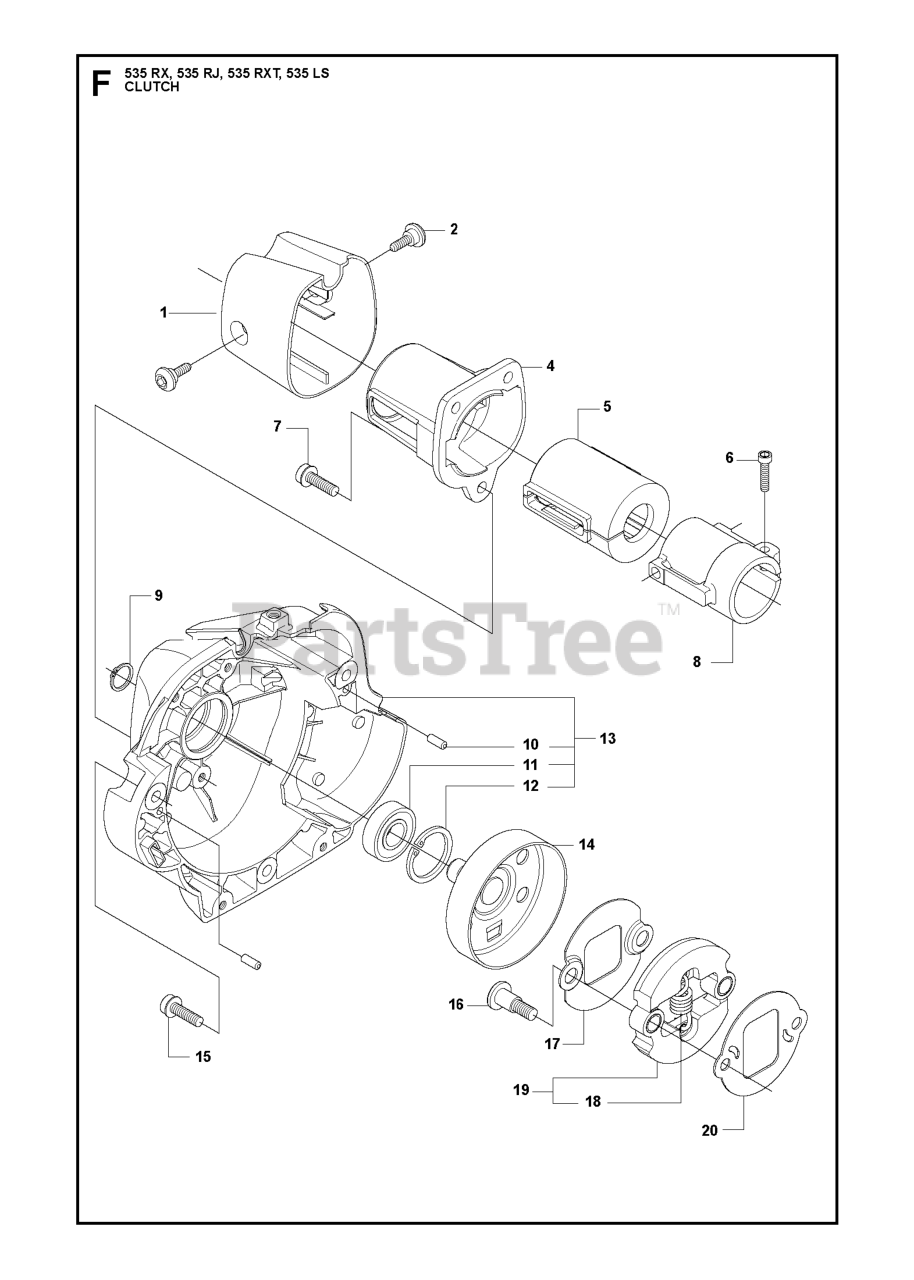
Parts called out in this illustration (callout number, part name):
1	COVER
2	SCREW MT5X11
4	HOLDER, TUBE
5	VIBRATION ABSORBER
6	SCREW MC6S 5X25
8	SLEEVE, COVER
8	LOCKING SLEEVE
9	SEEGER CLIP
11	BALL BEARING
12	RETAINING RING SGH 28
13	CLUTCH COVER
14	CLUTCH DRUM
16	SCREW CLUTCH
19	CLUTCH CPL
20	WASHER
